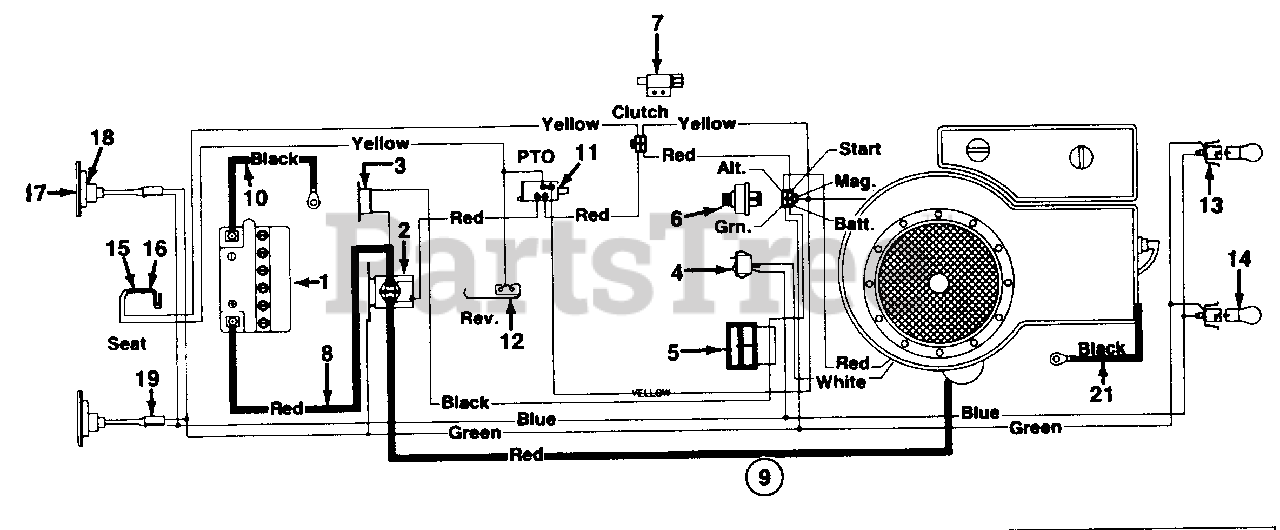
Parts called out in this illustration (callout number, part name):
1	Battery
2	Solenoid
3	Circuit Breaker
4	Light Switch
5	Ammeter
6	Ignition Switch
7	Safety Switch
8	Electric Wire 8" Lg.
9	Wire Harness
10	Ground Wire 11.5" Lg.
11	Safety Switch
12	Safety Switch
13	Twist Lock Bulb Socket
14	Bulb
15	Safety Switch (Seat)
16	Safety Switch (Seat)
17	Taillight Bulb
18	Taillight
19	Taillight Harness
21	Ground Wire 7.5" Lg.
